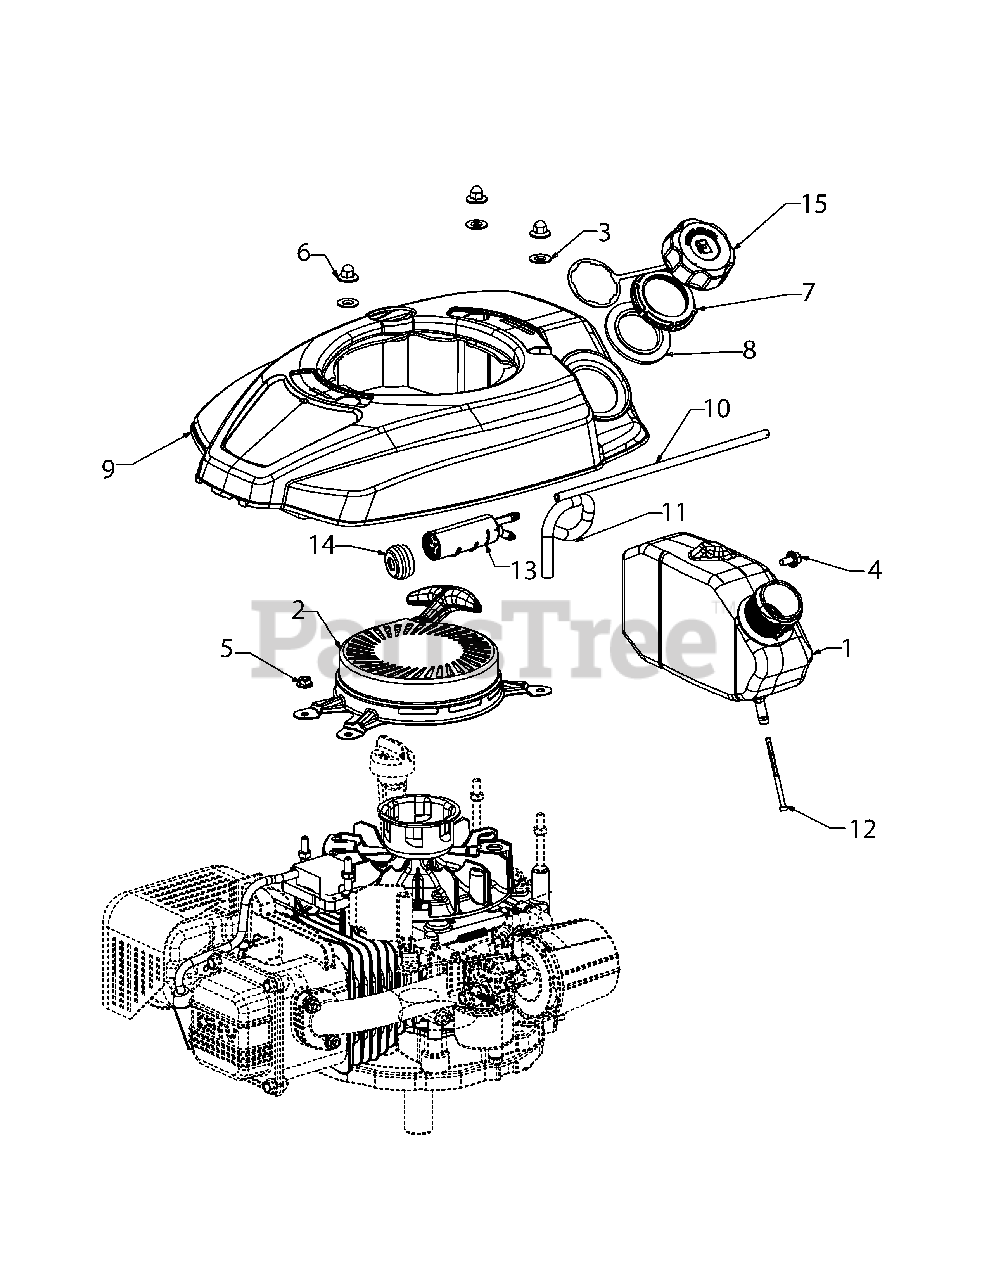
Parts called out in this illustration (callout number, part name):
2	Start Asm-Pull Rec
2	Pulley/Spring Asm
3	Spacer-Shroud 195
4	Hhflg-M6-1:12 Cl8.
5	Nut-Hex Flange M6-
6	Nut-Acorn M6-1
7	Fuel Tank Nut
8	Fuel Tank Lower Grommet
9	Shroud-Engine Reco
10	Hose-5 Id X 8 Od
11	Hose-5Mm Id Evap
11	Fuel Line Kit-5P71
12	Fuel Filter-Zs Ver
13	Carbon Canister
13	Canister/Carbon Asm
14	Carbon Canister Filter Cap
15	Fuel Cap Assembly
